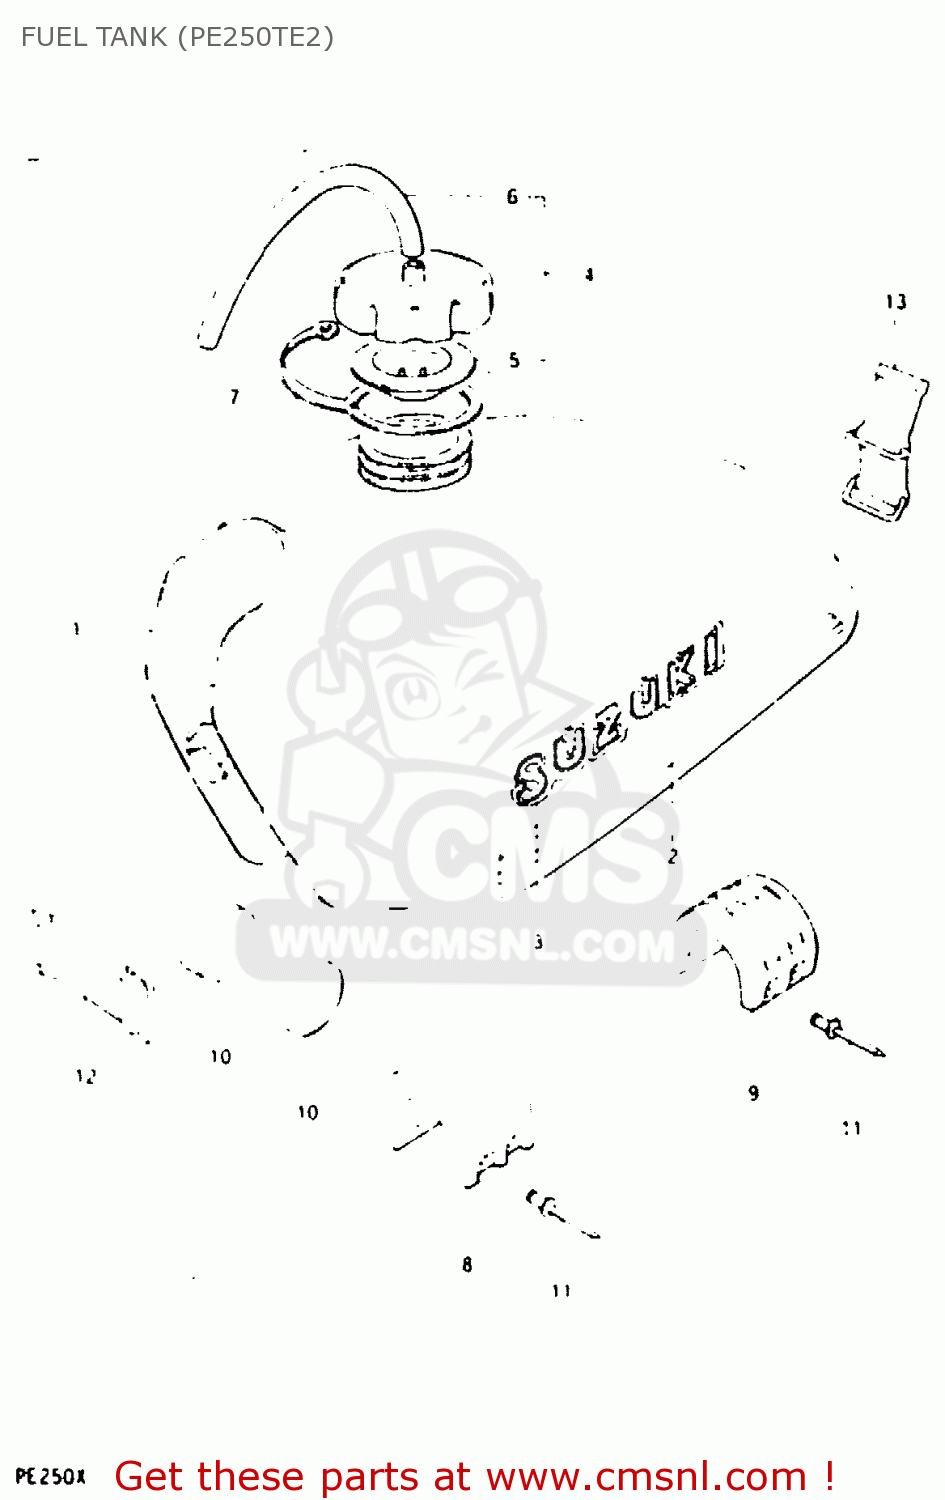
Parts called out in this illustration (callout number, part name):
1	TANK, FUEL (YELLOW)
2	TAPE SET
3	EMBLEM
4	CAP ASSEMBLY,FUEL TANK
5	GASKET,FUEL TANK CAP (NAS)
6	HOSE
7	BAND,FUEL TANK CAP
8	CUSHION, UPPER FRONT
9	CUSHION,FUEL TANK,CENTER
10	CUSHION
11	RIVET
12	BAND
13	BNAD, REAR
